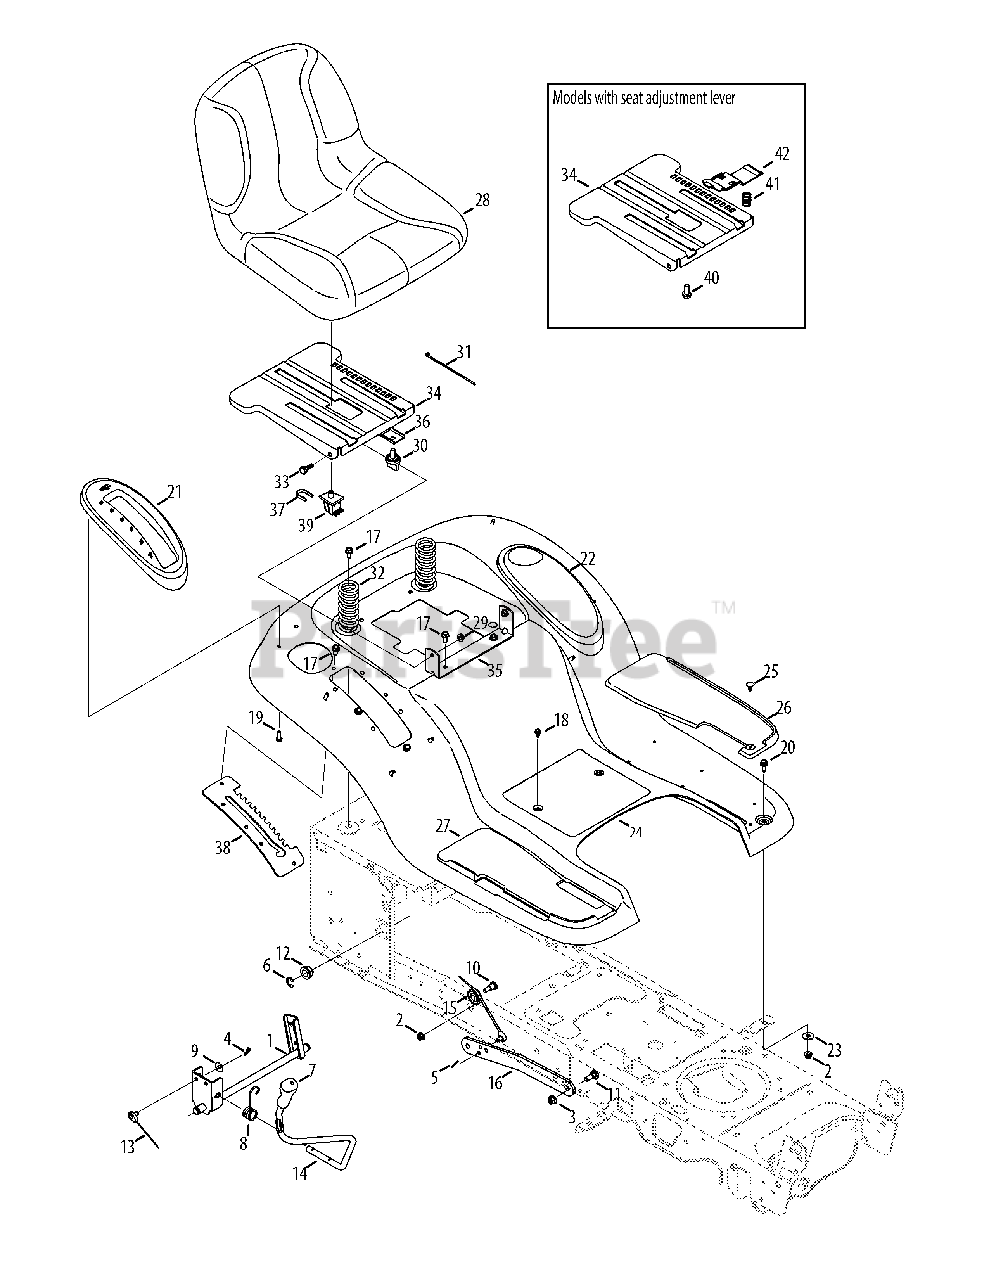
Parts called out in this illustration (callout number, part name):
1	Lift Shaft Assembly
2	Flangelock Nut, 5/16-18
3	Flangelock Nut, 3/8-16
4	Cotter Pin, .072 DIA. x 1.13 LG
5	Bow-Tie Cotter Pin
6	E-Ring, .625 DIA. SHAFT
7	Handle Grip
8	Torsion Spring
9	Spring Washer, .401 x .870 x .063
10	Shoulder Screw, .437 x .470x5/16-18
11	Shoulder Bolt, .500 x .270x3/8-16
12	Hex Flange Bearing
13	Lift Cable, 16.64 LG
14	Lift Handle
15	Pulley Roller Cable
17	Taptite Screw, Lock Washer, 5/16-18
18	Taptite Screw, Lock Washer, 1/4-20
19	Hi-Lo Screw, Lock Washer, 1/4-15
20	Taptite Screw, 5/16-18x.750
21	Lift Lever Cover
22	Cover with Cup Holder
23	Flat Washer, .344 x 1.00 x .063 HDN
25	Ratchet Clip
26	LH Foot Pad
27	RH Foot Pad
28	Seat, High Back
29	Flangelock Nut, 5/16-18
31	Cable Tie, 3/16 x .05 x 7.4
32	Compression Spring, 1.50 x 3.90 x .200
33	Shoulder Screw, .437 x .268x5/16-18
34	Seat Mounting Bracket
35	Seat Pivot Bracket
36	Knob Adjust Bracket
37	Switch Retainer Clip
38	Lift Bracket, 5 Style
39	Seat Switch
40	Hex Head Flange, 3/8-16x.875
41	Compression Spring, .68 x 1.065 x .055
42	Seat Adjustment Lever
